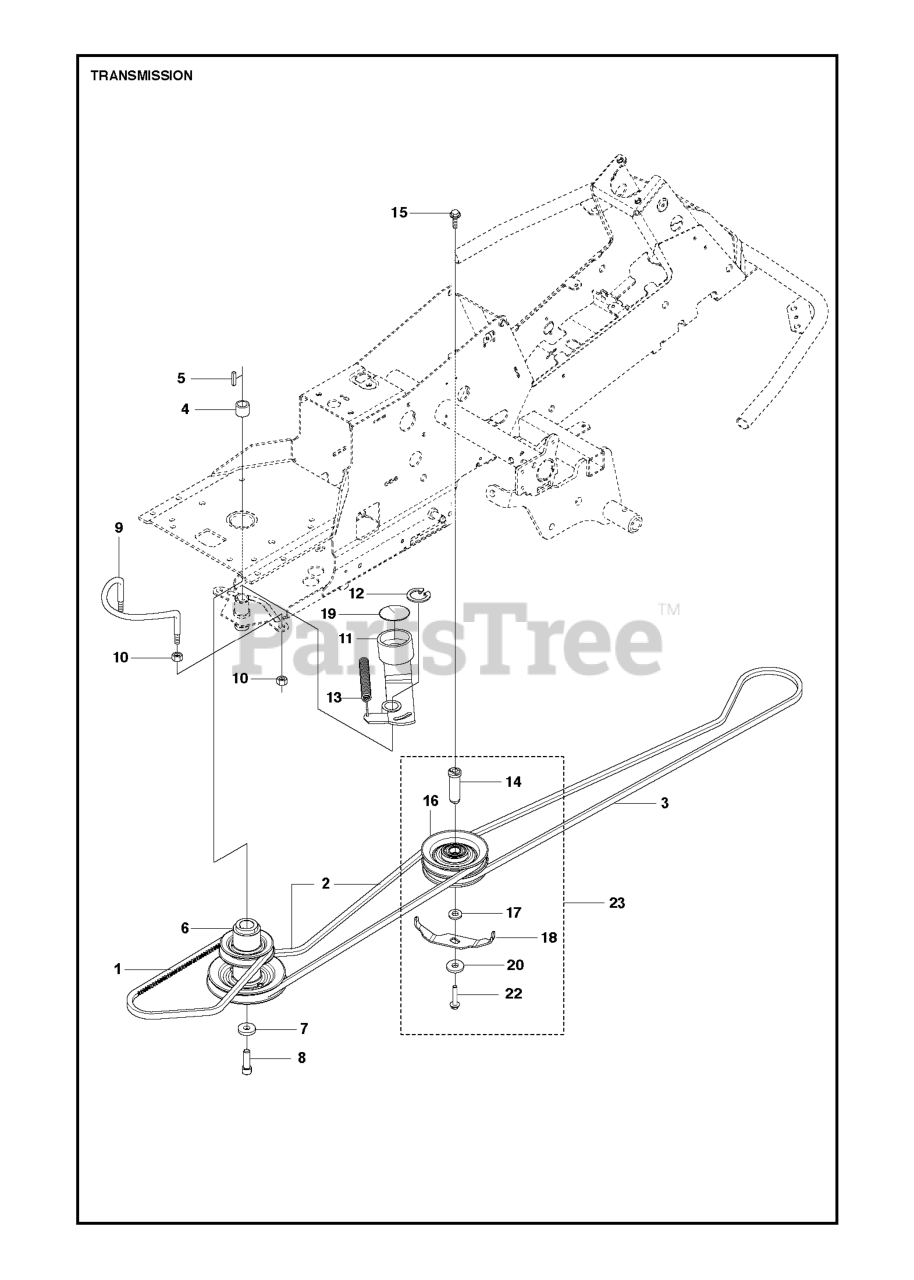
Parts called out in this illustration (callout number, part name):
9	BELT GUIDE
10	NUT
12	RETAINING RING SGA 25
17	WASHER
17	Screw M10x25
18	BELT GUIDE
20	WASHER
22	BOLT
